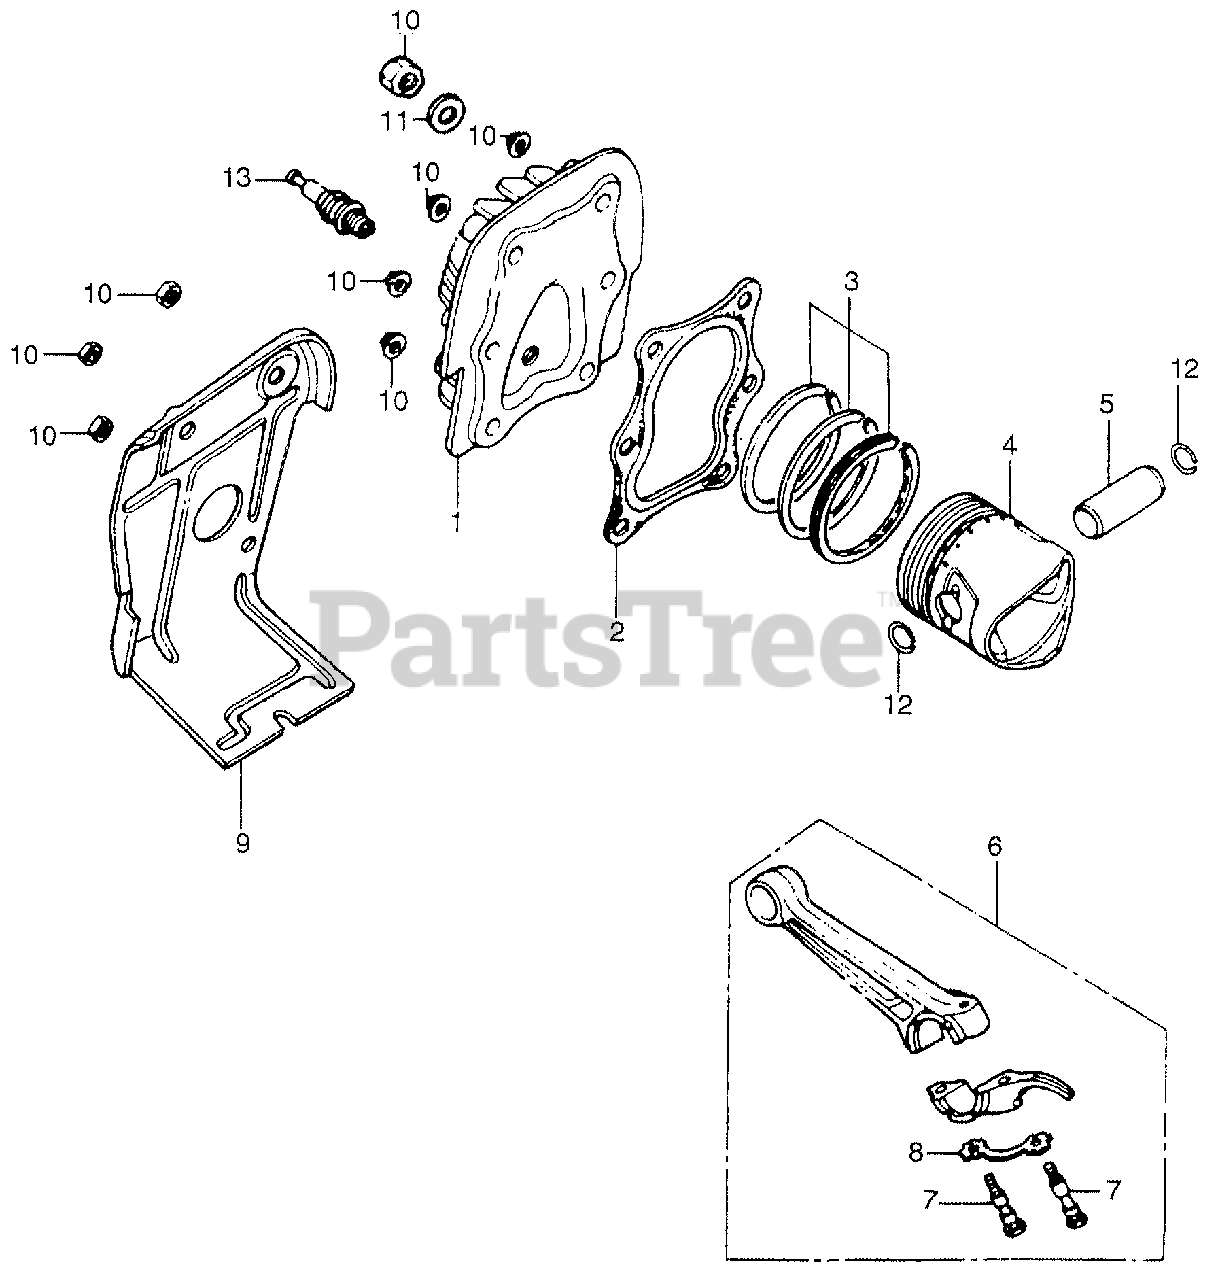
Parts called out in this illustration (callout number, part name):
1	CYLINDER HEAD
2	GASKET, CYLINDER HEAD (NOT AVAILABLE)
3	RING SET, PISTON (STD)
3	RING SET, PISTON (OS 0.25)
3	RING SET, PISTON (OS 0.50)
3	RING SET, PISTON (OS 0.75)
4	PISTON (STD)
4	PISTON (OS 0.25)
4	PISTON (OS 0.50)
4	PISTON (OS 0.75)
5	PIN, PISTON
6	ROD ASSY., CONNECTING
7	BOLT, CONNECTING ROD
8	PLATE, LOCK (NOT AVAILABLE)
9	VANE B, GUIDE
10	NUT, FLANGE (6MM) (NOT AVAILABLE)
12	CLIP, PISTON PIN (13MM)
13	SPARK PLUG (CM6) (NGK)
